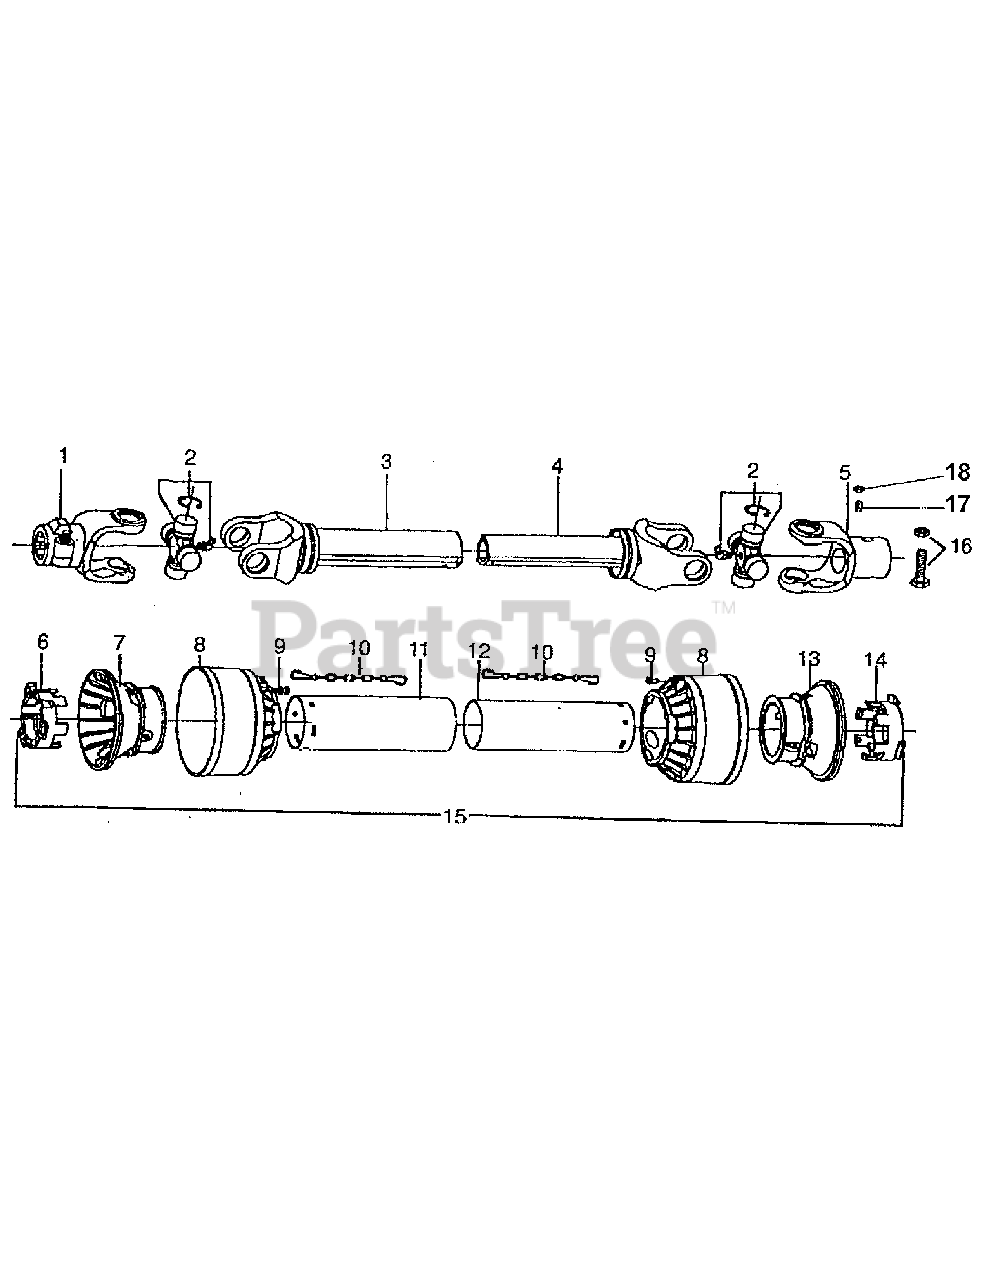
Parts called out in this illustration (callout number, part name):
1	YOKE ASSEMBLY (TRACTOR END)
2	CROSS ASSEMBLY
3	OUTER TUBE W/YOKE
4	INNER TUBE W/YOKE
5	YOKE ASSEMBLY (IMPLEMENT END)
6	TUBE BEARING, OUTER
7	OUTER TUBE RIGID CONE
8	SOFT CONE
9	PIN, STOP ROTATION
10	ANTI-ROTATION CHAIN
13	INNER TUBE W/RIGID CONE
14	TUBE BEARING, INNER
15	SHIELD, COMPLETE
16	3/8" X 3" GR2 SHEAR BOLT W/NUT
17	1/4" SET SCREW
18	1/4" HEX NUT
